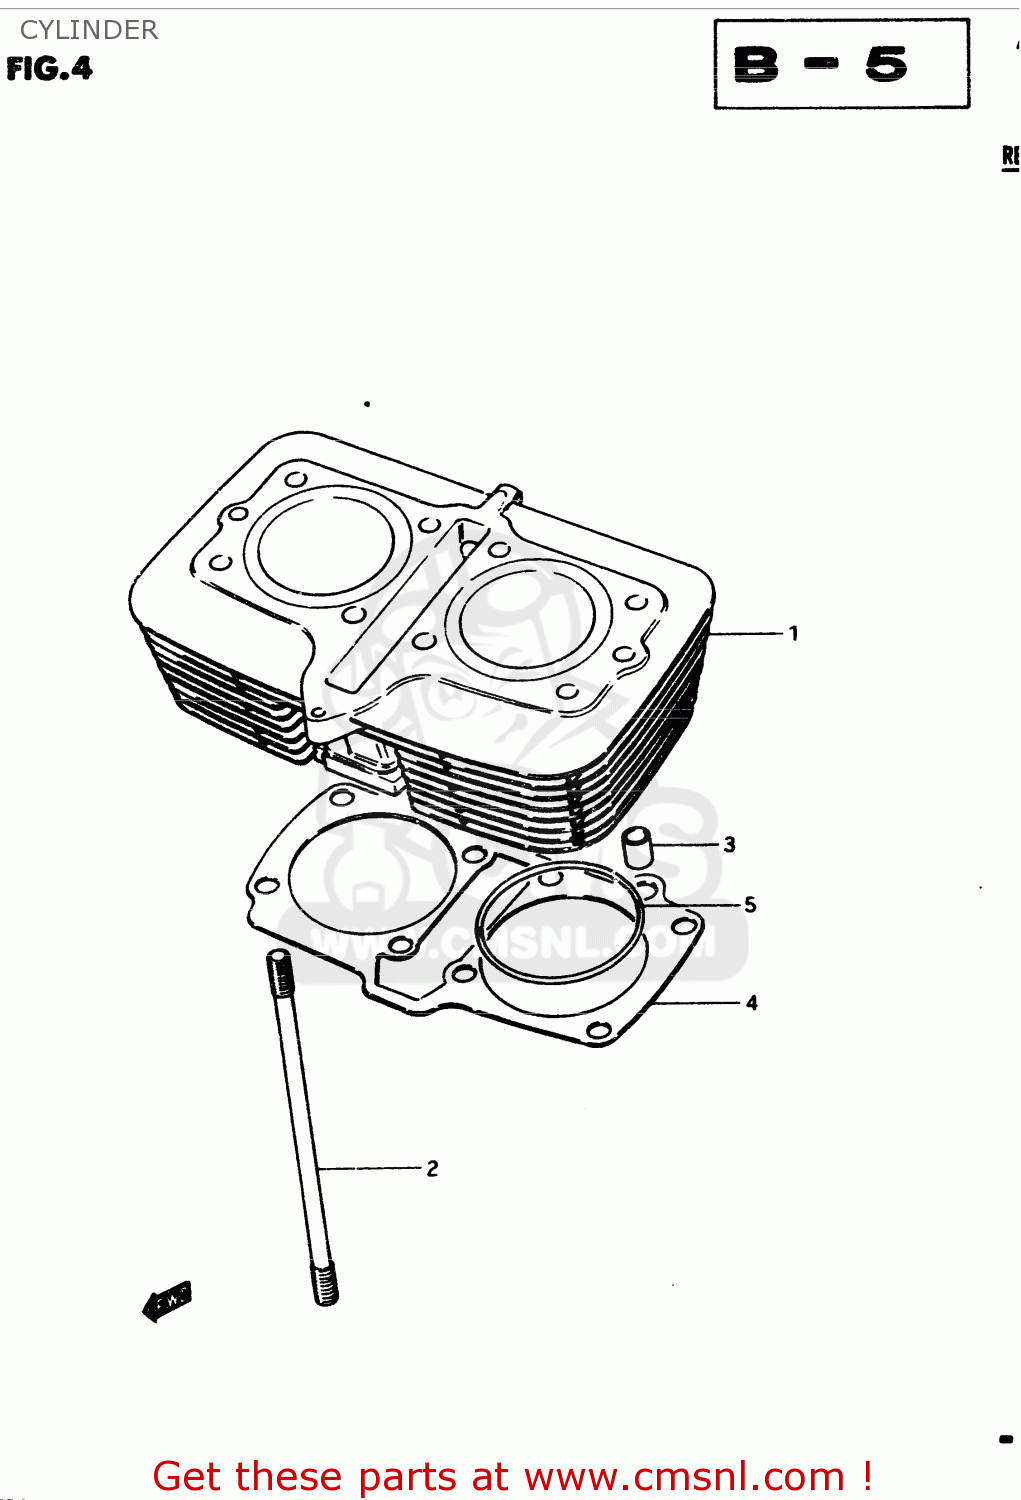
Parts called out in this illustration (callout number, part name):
1	CYLINDER
2	STUD
3	PIN
4	GASKET,CYLINDER (MCA)
5	O RING(D:2,ID:74)
